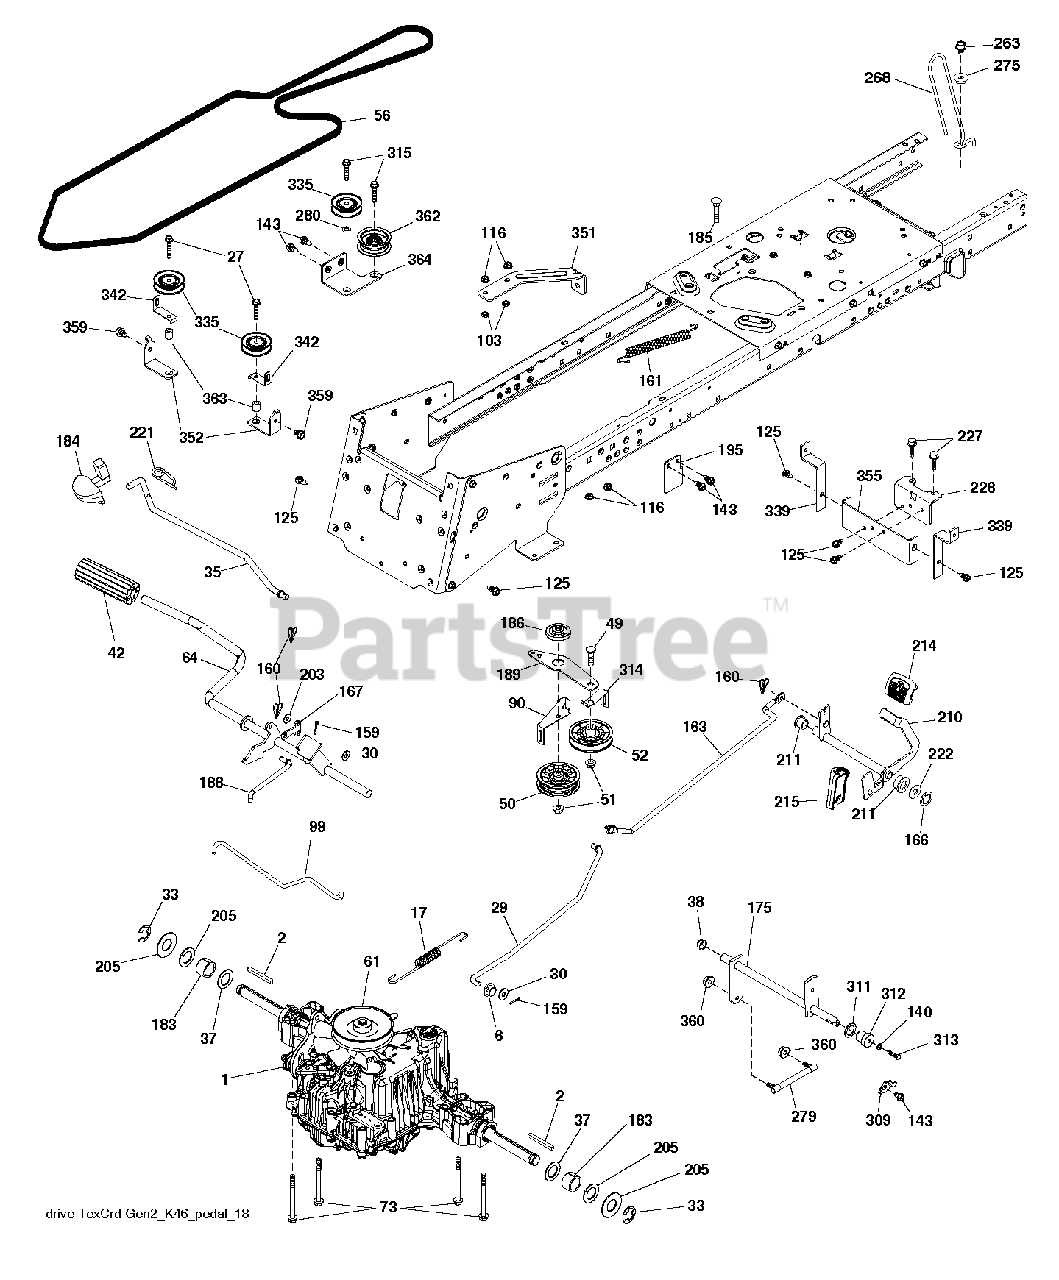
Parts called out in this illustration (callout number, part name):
2	SQUARE KEY
6	GROMMET T
33	E-RING LT
35	Parking Brake Rod, GT Husq
37	WASHER.HARDENED
38	NYLINER SNAP 5/8" ID
42	PEDAL COVER T
49	BOLT
50	IDLER.FLAT.910.OFFSET
51	NUT LOCK FLG 3/8-16 UNC
52	IDLER.V-GROOVE.910.OFFSET
64	SHAFT.ASM.PEDAL.BRK.CNTR
73	BOLT HEX 5/16-18 GR 5
103	JAM NUT TI
116	NUT LOCK HEX FLANGE 5/16-18
125	SCREW
140	LOCKWASHER
159	COTTER PIN
160	RETAINER CLIP
161	SPRING, RETURN LT
166	NUT.PUSH.625
167	LATCH.BRAKE.SPRING
183	SPACER AXLE
184	Parking Brake Handle
186	SPACER.RETAINER
188	LINK.CLUTCH.GROUND.DRIVE
203	WASHER
210	ROCKER.ASM.PEDAL.CONTR
211	BEARING.NYLON
214	PAD PEDAL FORWARD
221	RETAINER.SPRING.CLIP.H
222	WASHER 21/32 X 1-1/4 X 10 GA.
226	BRACKET.MOUNT.TORQUE.K46.TLT
227	SCREW
263	SCREW, 3/8-16X3/4
275	WASHER
309	PLATE FASTENING LT
311	WASHER NYL
315	BOLT.5/16-18X1.25
335	PULLEY.V-IDLER.
359	SCREW LT.3/8-46X5/8
